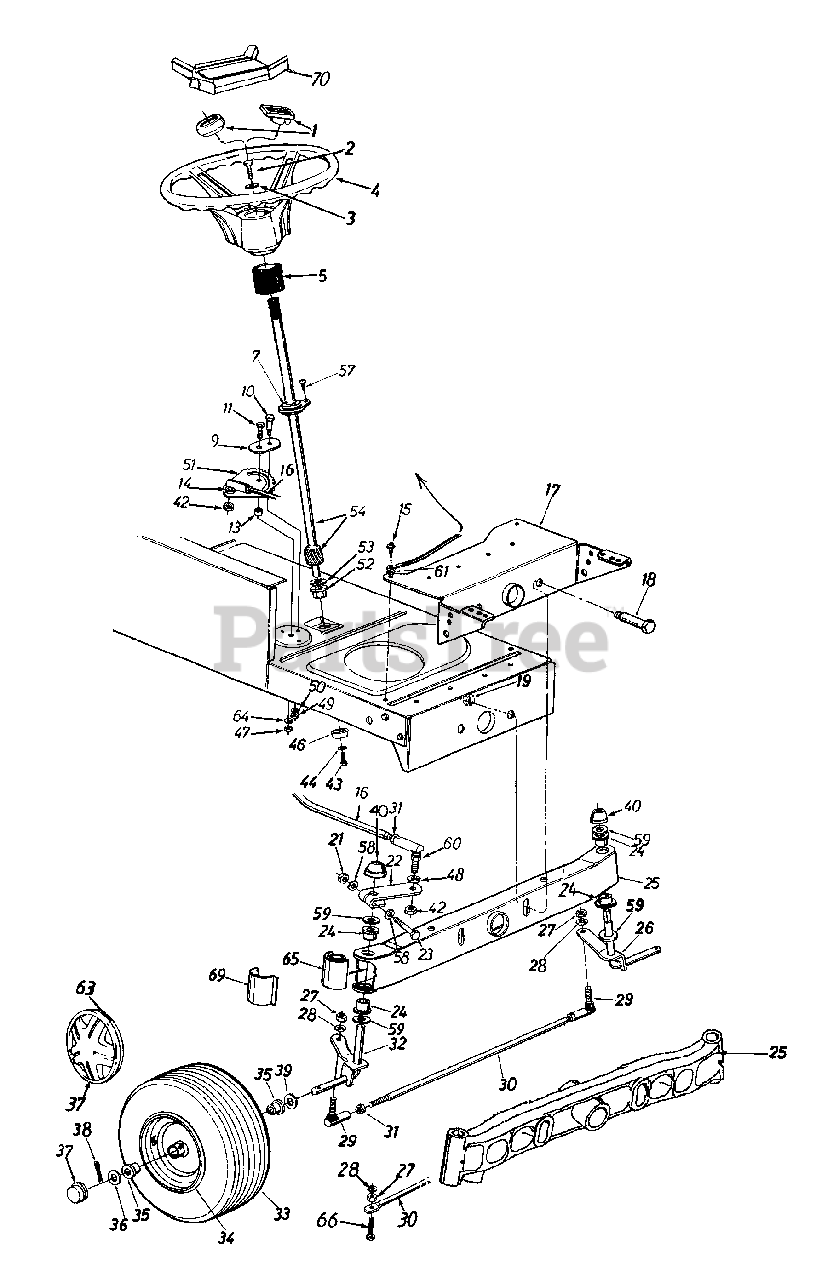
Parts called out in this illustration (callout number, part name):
1	Steering Wheel Cap
2	Hex Bolt 5/16-18 x 1" Lg.
3	Belleville Wash. .345" I.D.
4	Steering Wheel
5	Steering Bellow- 4.5"
7	Flange Bearing .628" I.D. x 1.36 O.D.
9	Retainer Plate
10	Shoulder Bolt .437 x .35 Lg. 5/16-18
11	Hex Bolt 3/8-24 x 1.0" Lg. (Gr. 5)
13	Spacer .380" I.D. x .625" O.D.x
14	Lock Washer 3/8" I.D. (H.D.)
15	Hex Wash. Hd. Self-Tap Scr.
16	Steering Drag Link
18	Shoulder Bolt
19	Flanged L- Nut 3/8-16 Thd.
21	Hex Lock Nut 5/16-24 Thd.
22	Steering Arm Front Axle
23	Hex Bolt 5/16-24 x 2.25" Lg.
24	Hex Flg. Brg. .632 I.D.
26	Front Axle Assembly-LH
27	Hex Nut 3/8-24 Thd.
28	Lock Washer 3/8" I.D.
29	Ball Joint 3/8-24 Thd.
30	Tie Rod
31	Hex Jam Nut 3/8-24 Thd.
32	Front Axle Assembly-RH
36	Flat Washer .635 I.D. x 1.59" O.D.
37	Front Wheel Hub Cap
38	Cotter Pin 1/8" Dia. x 1.25"
39	Flat Washer .640" I.D. x 1.20" O.D.
40	Push Cap 5/8" Dia. Rod
42	Hex Jam Nut 3/8-24 Thd.
43	Hex Patch Bolt 5/16-18 x .62"
46	Cap
47	Hex Cent. Lock Nut 3/8-24 Thd.
48	Lock Washer 3/8" I.D.
49	Hex Cent. Lock Nut 5/16-18 Thd.
50	Lock Washer 5/16" I.D.
51	Steering Gear Segment
52	Hex Flg. Brg. .634 I.D.
53	Flat Washer (Hardened)
54	Steering Shaft
57	Oval Hd. C.Sunk Scr.
58	Wave-Wash. .32" I.D. x .62" O.D.
59	Flat Washer (Hardened)
60	Drag Link Ball Joint 7/16-20 Thd.
63	Spring Clip
64	Washer .39" I.D. x 1.38" O.D.
65	Pivot Bar End Cap
66	Hex Bolt 3/8-24 x 1.5" Lg. (Gr. 5)
69	Axle Cap
70	Steering Wheel Insert
